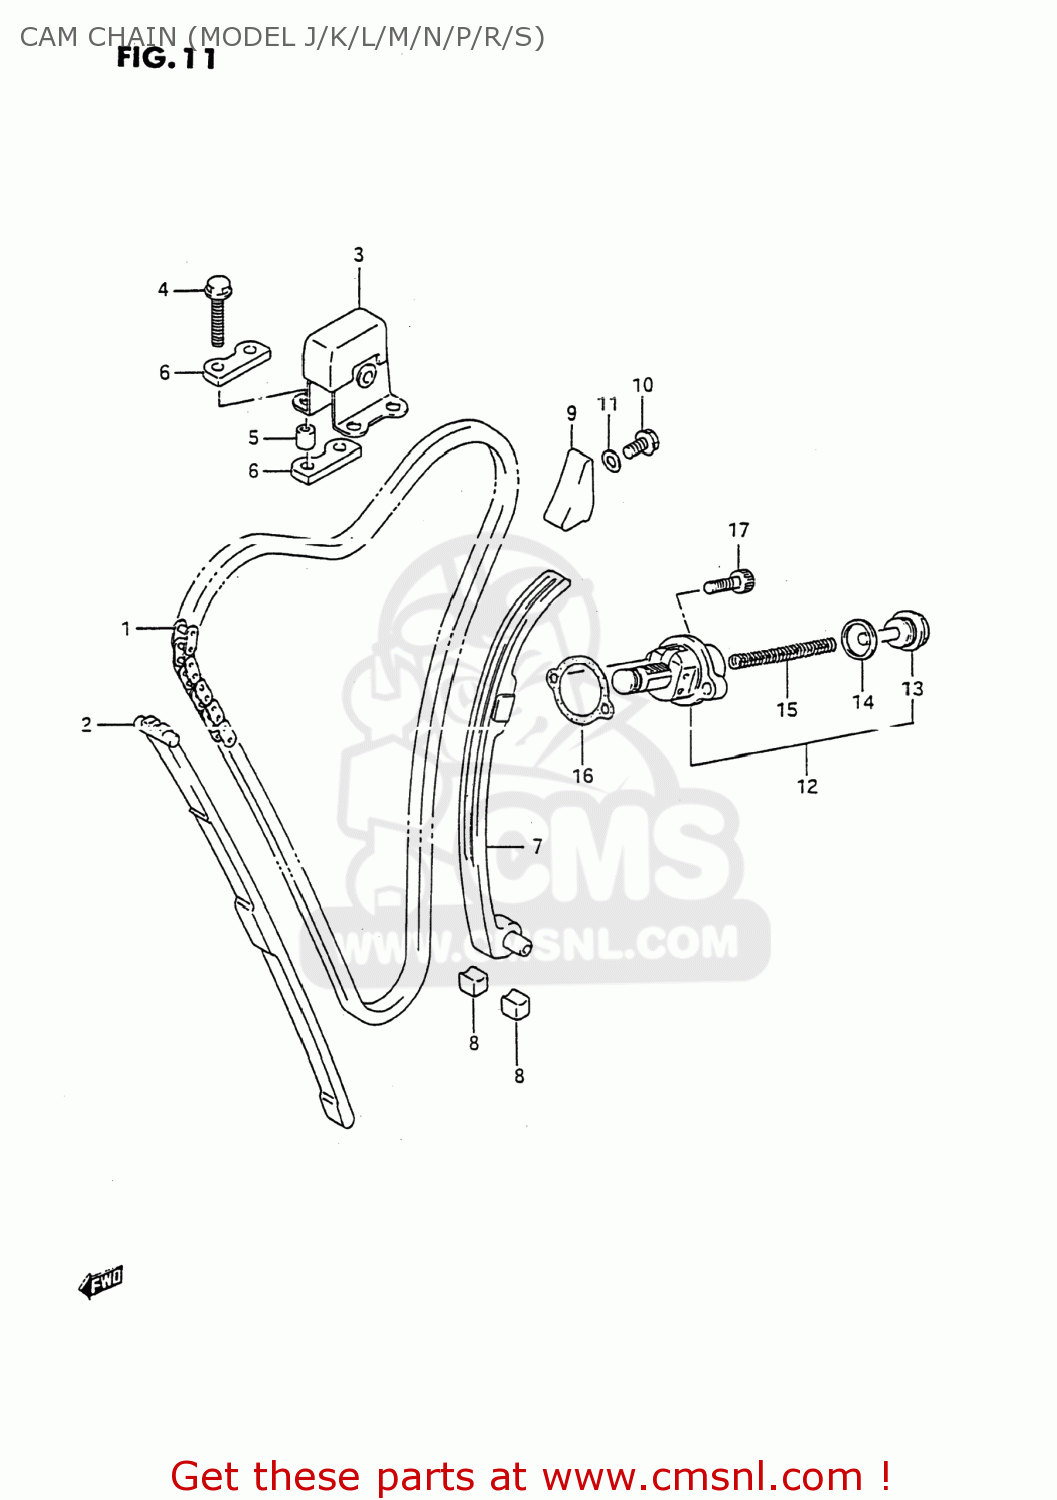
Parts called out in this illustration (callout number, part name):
1	CHAIN,CAMSHAFT DRIVE
2	GUIDE,CAM CHAIN NO.1
3	IDLER,CAM CHAIN
4	BOLT
5	SPACER (6,8X10X9.4)
6	CUSION,IDLER
7	TENSIONER,CAM CHAIN
8	CUSHION,CAM CHAIN TENSIONER
9	GUIDE,CAM CHAIN NO.2
10	BOLT
11	GASKET(5.8X13X1.2) (NAS)
12	ADJUSTER ASSY,TENSIONER
13	PLUG
14	GASKET (NAS)
15	SPRING
16	GASKET,TENSIONER ADJUSTER (NAS)
17	BOLT
